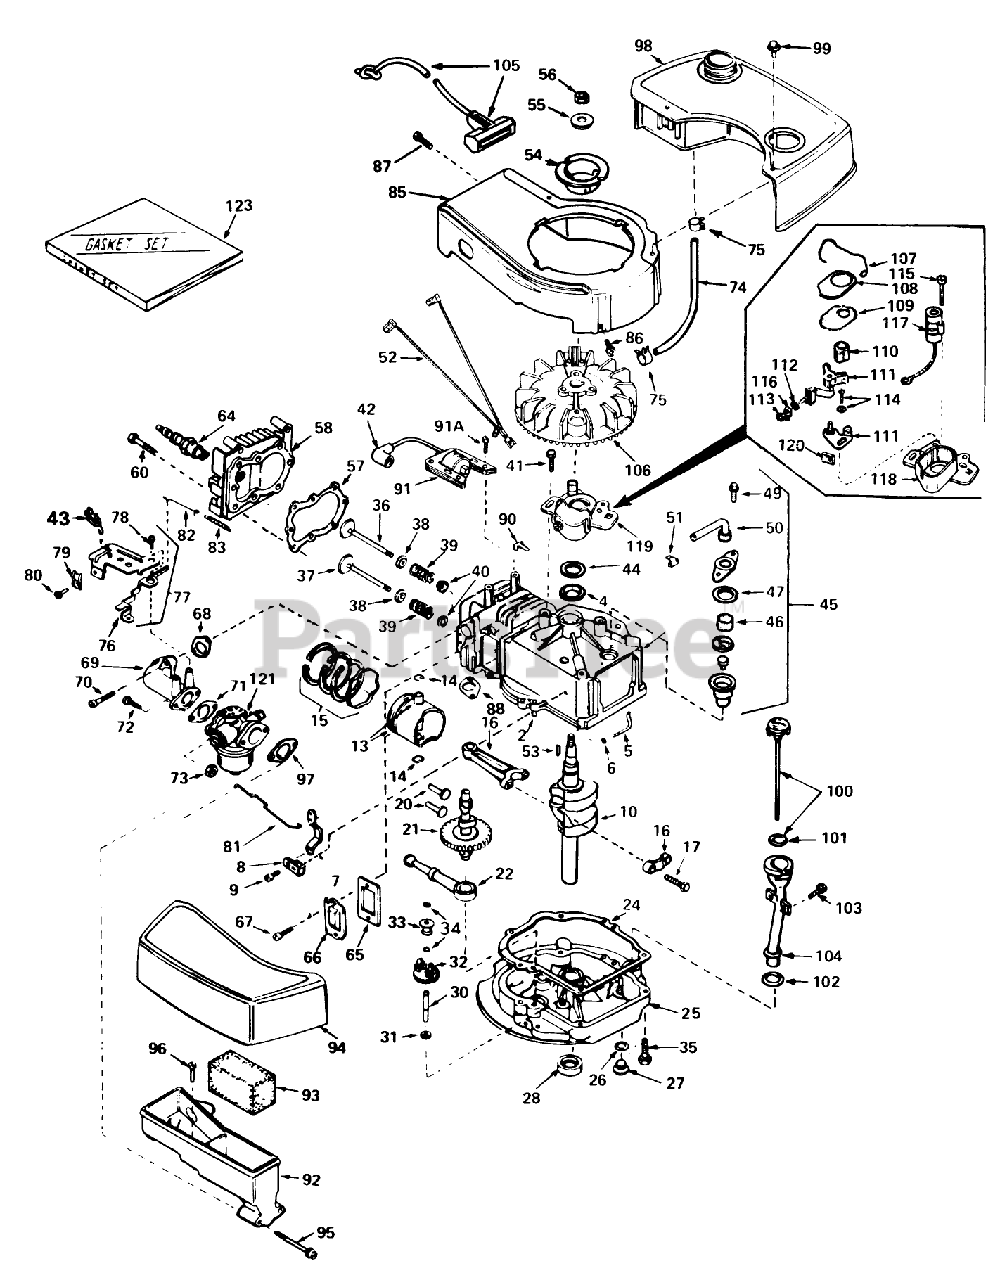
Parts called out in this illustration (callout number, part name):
1	Cyiinder Assy. (Incl. Ref. #2, 4 105)
2	Pin-Dowel
4	Seal-Oil
5	Rod, Governor (Incl. No. 36)
6	Washer-Flat
7	Governor Lever
8	Clamp-Lever, Governor
9	Screw
10	Crankshaft
13	Piston Pin Assy. (Incl . Ref. . #14) (Std.)
13	Piston, Pin Ring Assy. (Std.)(Incl. Ref. #13A, 14 15)
13	Piston Pin Assy. (Incl. Ref. #14) (.010 Oversize)
13	Piston,Pin Ring Assy. (.010 over-size)(Incl. Ref. #13A, 14 15)
13	Piston Pin Assy. (.020 oversize) (Incl. Ref. #14)
13	Piston, Pin Ring Assy. (Incl. Nos. 13A, 14 15)(.020 oversize)
14	Ring-Retaining, Piston Pin
15	Ring Set Piston (Std.)
15	Ring Set Piston (.010 Oversize)
15	Ring Set Piston (.020 Oversize)
16	Rod Assy., Connecting (Incl. Ref. #17)
17	Bolt-Rod, Connecting
20	Lifter-Valve
21	Camshaft(Mech.Comp. Release)
22	Oil Pump ASM
24	Gasket, Mounting
25	Flange Assy., Mounting (Incl. Ref. #26thru 30)
26	Gasket-Oil Drain
27	Plug Oil Drain
28	Seal Oil
30	Shaft-Governor
31	Washer-Flat
32	Governor Gear ASM
33	Spool-Governor
34	Ring-Retaining
35	Screw (1/4-20 x 1-1/4)
36	Valve, Intake (Incl. Ref. #38, 39 40) (Std.)
36	Valve, Exhaust (1/32" Oversize) (Incl. Nos. 8, 9 10)
37	Valve, Exhaust (Standard) (Incl. Nos. 8, 9 10)
37	Valve, Exhaust (1/32" Oversize) (Incl. Nos. 8, 9 10)
38	Cap-Upper Valve Spring
39	Spring-Valve
40	Cap-Valve, Spring
41	Screw
42	Cover-Spark Plug
43	Terminal
44	Gasket Stator
45	Breather Assy. (Incl. Ref. #46, 47, 49, 50 51 )
46	Element-Breather
47	Gasket-Breather
49	Screw, Hex Hd. w/Conical
50	Tube, Breaker
51	Clip, Breather
52	Wire Ground
53	682488 LB GRASS HI-
54	Hub-Starter
55	Washer-Belleville
56	Nut-Flywheel
57	63573 GIL 42 SNWTHW
58	Head-Cylinder
60	Screw (5/16-18x1-1/2)
64	Plug, Spark (J17LM or equiv.)
64	Plug, Spark (Champion RCJ-8)
65	Gasket-Breather
66	Cover-Valve
67	Screw
68	Gasket, Intake
69	Pipe, Intake
70	Screw (1/4-20 x 1)
71	Gasket-Carburetor
73	Nut and Lock Washer (1/4-28)
74	Line-Fuel
75	Clamp-Line, Fuel
76	Lever Control
77	Control Assy., Speed (Incl. Nos, 76, 78 89)
78	Screw, Hex Washer Hd Shoulder Self-Tap
79	Conduit
80	Screw (10-32 x 3/8)
81	Link-Throttle
82	Link Governor Spring
83	Spring Governor
85	Housing Blower
86	Screw
87	Screw (10-24 x 9/16)
88	Gasket Exhaust
90	Clip-Wire
91	Lamination Coil Assy. (Incl. No. 42)
91A	Screw
92	Body Air Cleaner
93	Filer, Air
94	Cove, Air Cleaner
95	Screw Fil Hd.
96	Screw, Hex Hd.
97	Gasket-Air Cleaner
98	Tank, Fuel
99	Screw (10-32 x 35/64)
100	Dipstick, Oil (Incl. Ref. #101)(Twist Lock)
101	O-Ring
102	Gasket
103	Screw (10-32 x 1/2)
104	Tube-Oil Fill
105	Rope Assy., Starter
106	FIywheel
107	Spring Breaker Box
108	Cover-Dust
109	Gasket-Dust Cover
110	Cam-Breaker
111	Breaker Assy.
112	Washer
113	DECAL
114	Breaker Screw
115	Condenser Screw
116	Terminal, Ground
117	Condenser
118	Stator Plate
119	Stator Plate Assy. (incl. Nos. 107, 111 thru 118 120)
120	Felt,Cam Wiper
121	Carburetor (Incl. Ref. #71 )
123	53024/VAR.16HP O/P
